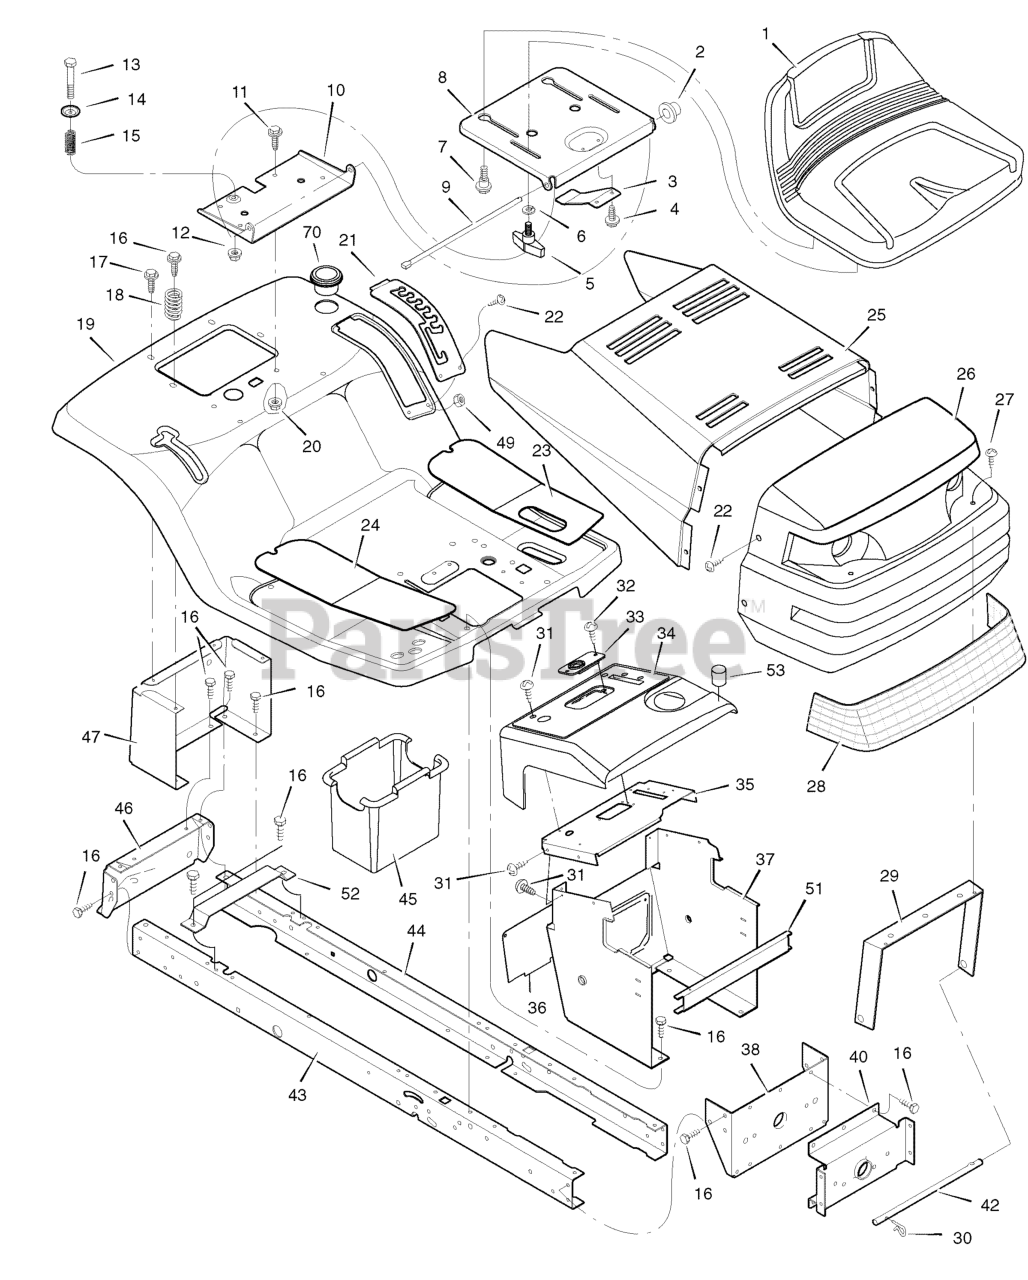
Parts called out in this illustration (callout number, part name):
1	Seat
2	Cap, Push 0n
5	Bolt, Wing
6	Washer
7	Bolt, Shoulder
8	Support, Seat
9	Rod, Pivot
10	Bracket, Pivot
11	Bolt
13	Bolt, Shoulder
20	Nut
21	Plate, Index
23	Mat, Left
24	Mat, Right
26	Grille
27	Screw, 1/2 x .75
28	Lens
29	Brace, Grille
30	Pin, Hair
33	Bearing, Steering
35	Plate, Dash
36	Panel, Access
37	Support, Dash
38	Bracket, Rear Hanger
40	Axle, Hanger
42	Rod, Pivot
43	Frame, Right
44	Frame, Left
45	Container, Battery
46	Plate, Hitch
47	Panel, Rear
52	Support, Battery
55	Fastener, Panel
70	Holder, Cup
